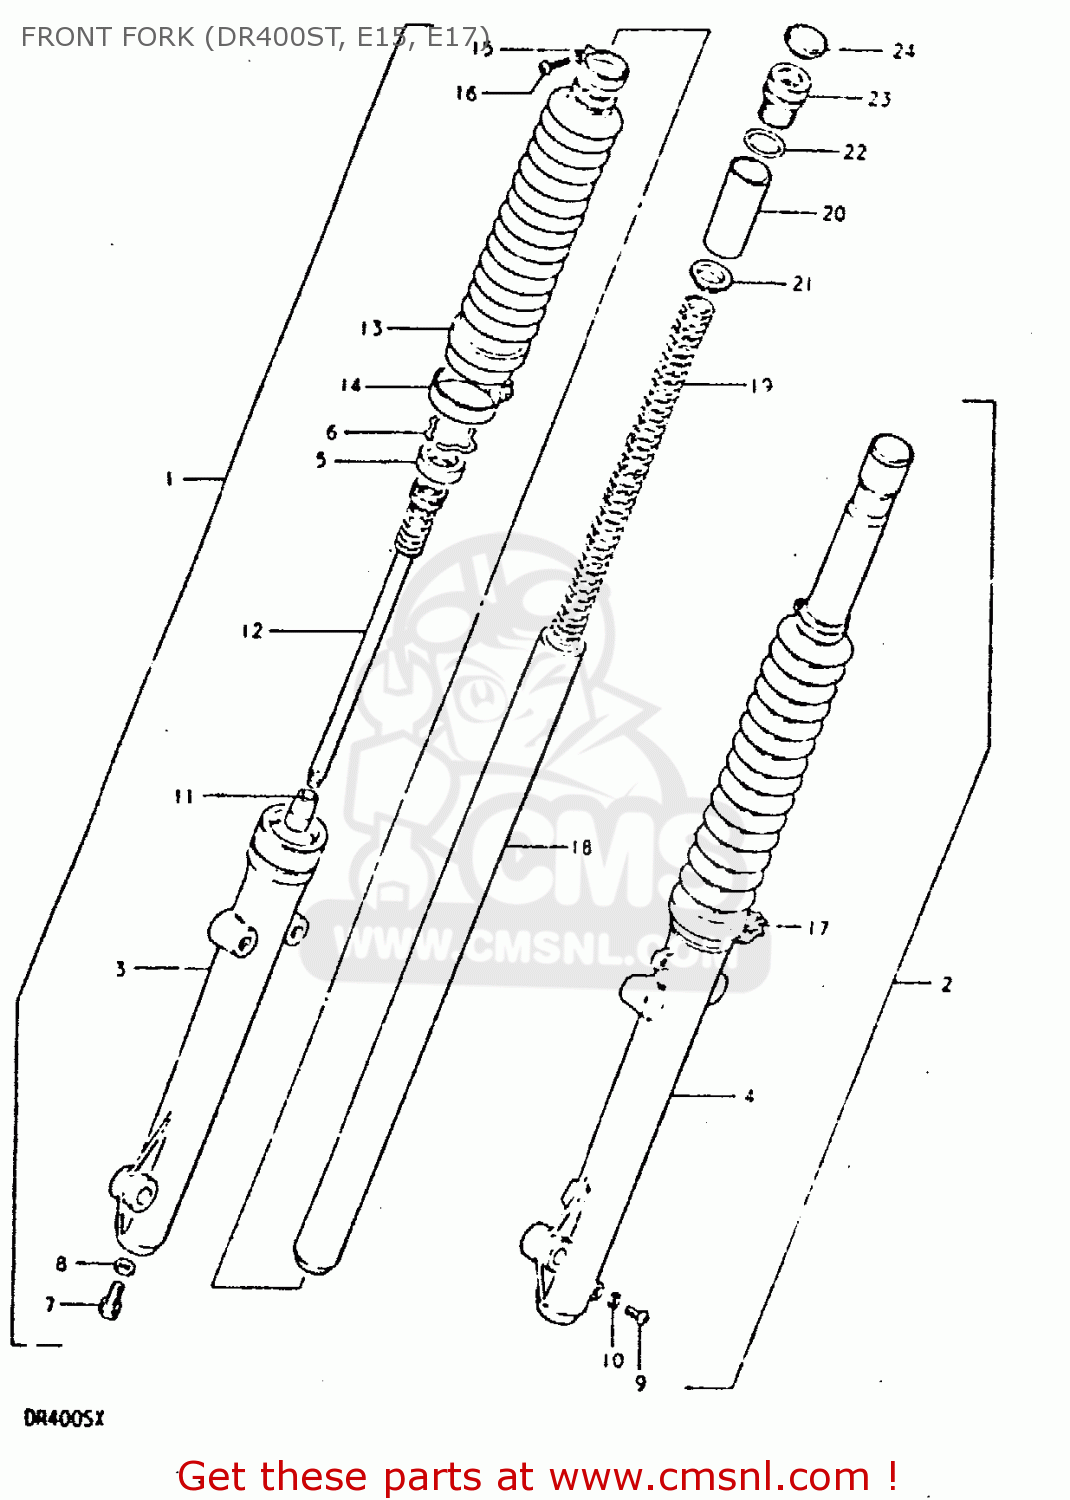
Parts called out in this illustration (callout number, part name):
1	DAMPER ASSY, RH
2	DAMPER ASSY, LH
3	TUBE,OUTER,RIGHT
4	OUTER TUBE, LH
5	OIL SEAL,FRONT FORK
6	7
7	BOLT,FORK CYLINDER(10X25)
8	GASKET (NAS)
9	SCREW
10	GASKET,DRAIN,PLUG (NAS)
11	PIECE,OIL LOCK
12	CYLINDER,FRONT FORK
13	BOOT
14	BAND,FRONT FORK COVER
15	BAND,BOOT
16	SCREW
17	BAND,FORK COVER BOOT
18	INNER TUBE
19	INNER TUBE, LH
20	SPRING
21	SPACER,SPRING
22	GUIDE,FRONT FORK SPRING C
23	O RING
24	CAP,FORK INNER TUBE
25	CAP,FRONT FORK
